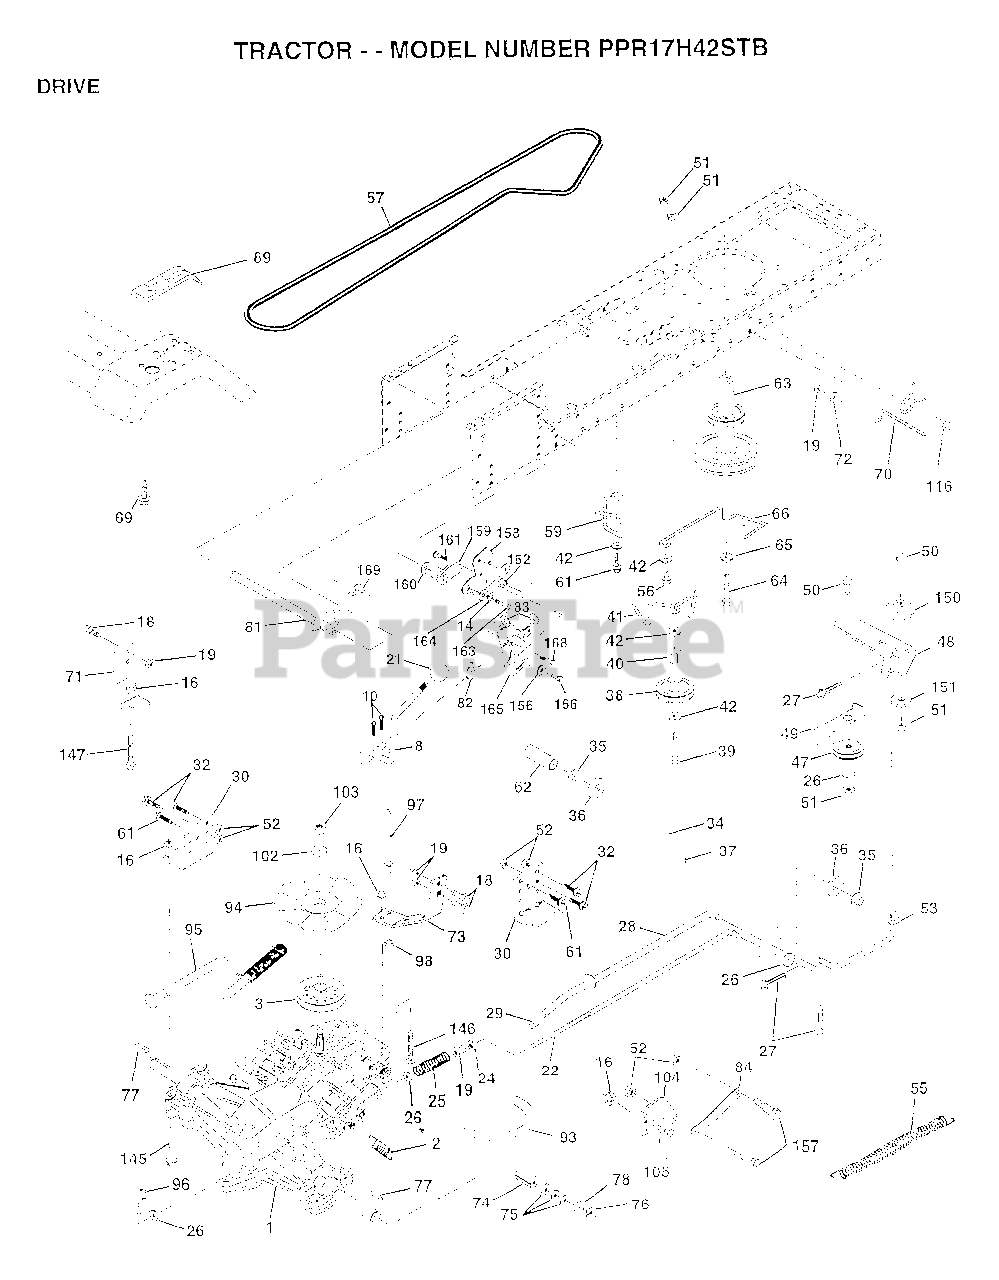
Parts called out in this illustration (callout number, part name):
2	SPRING RET BRAKE
3	PULLEY.TRANSAXLE
8	ROD.SHIFT.FENDER.ADJ.LT.CRD
10	PIN COTTER 1/8
14	LOCKWASHER
16	NUT
18	BOLT
19	NUT
21	KNOB DLX BLK/BLK
22	ROD.BRAKE.HYDRO.
24	NUT
25	SPRING ROD LT
26	WASHER
27	COTTER PIN
28	ROD.BRAKE.PARK.LT
29	PLUNGER CAP T
30	TRANSAXLE MTG BKT
32	BOLT
34	SHAFT ASM-PEDAL F
35	NYLON BEARING
36	WASHER LT
38	FLAT IDLER PULLEY
39	BOLT
40	SPACER T
41	"KEEPER,BELT.IDLER FLAT"
42	WASHER
48	BELLCRANK.CLUTCH
49	RETAIN BELT
53	"LINK, CLUTCH T"
55	"SPRING, RETURN LT"
57	"BELT.GD DRV 82"""
59	KEEPER BELT CNTSP
61	SCREW
62	PEDAL COVER T
63	PULLEY.ENGINE
64	BOLT
65	LOCKWASHER
66	KEEPER-BELT
69	SCREW HEXWSH H-L
70	KEEPER BELT ENG
71	STRAP TORQ LH HYD
72	WASHER
73	"STRAP-TORQUE,RH"
74	SPACER SPLIT
75	WASHER
76	E-RING LT
77	SQUARE KEY
78	WASHER
81	SHAFT.ASM.CROSS
82	"SPRING,TORSION"
83	WASHER
84	LINK.TRANSAXLE.LT/YT
89	CONSOLE.SHIFT.LT
93	"LINE FUEL HYD 4"""
94	"FAN 7"" HYDRO"
95	CONTROL.ASM.BYPASS.HYDRO.99
96	RETAINER M
97	BOLT KEEPER RH
98	NUT
102	WASHER BELLEVILLE
104	ARM CONTROL HYDRO
105	SCREW CAP 5/16-18
116	BOLT RDHD 3/8-16
145	BOLT.HEX.FLGHD
146	BOLT.HEX.FLGHD.
147	BOLT.HEX.FLGHD
150	BUSHING.BELLCRANK.GRD.DR
151	WASHER
156	WASHER.SRRTD.5/16
157	"BOLT,SHOULDER"
158	BRKT.SHIFT.MOUNT
159	HUB.SHIFT
160	WASHER
161	BOLT T
164	WASHER.5/8X.281X10GA
165	BRKT.PIVOT.LEVER
166	SCREW.5/16-18X5/8
168	BOLT.SHOULDER.5/16-18X.561
169	PLATE.FASTENING
